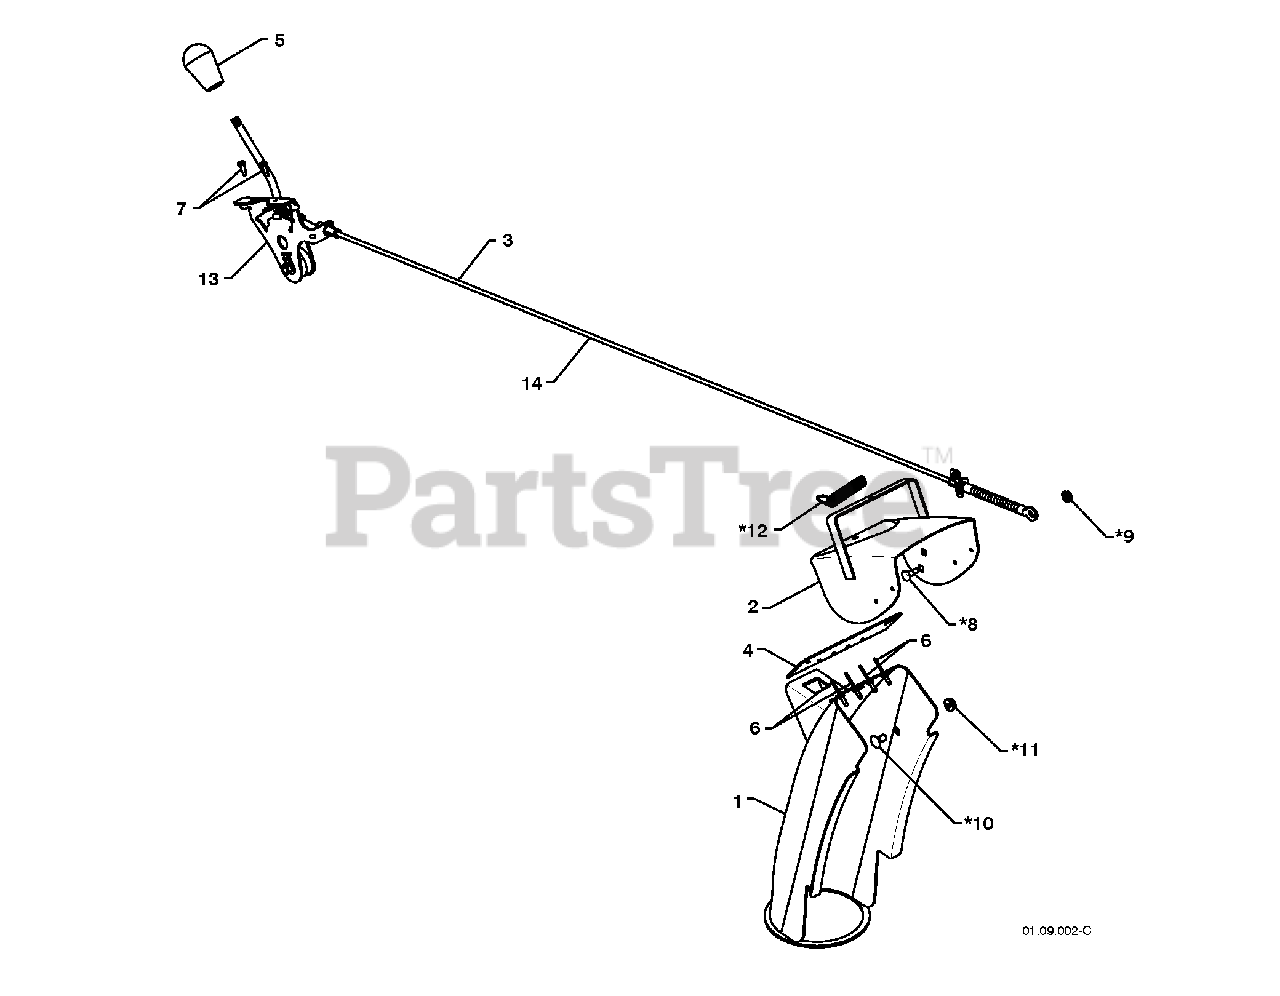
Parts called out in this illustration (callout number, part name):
3	CONTROL.ASM.DEFLECTOR
4	SEAL.DEFLECTOR
5	KNOB LEVER, BLACK
6	RIVET BLIND
7	SCREW #10-24 X 5/8
8	BOLT, SHOULDER
9	NUT.HEX.FLANGE.1/4
10	BOLT
11	NUT, LOCK 5/16-18
12	SPRING
13	CHUTE.DEFLECTOR.HEAD.SERVICE.
14	SERVICE.CHUTE.DEF.CBL.BLK
